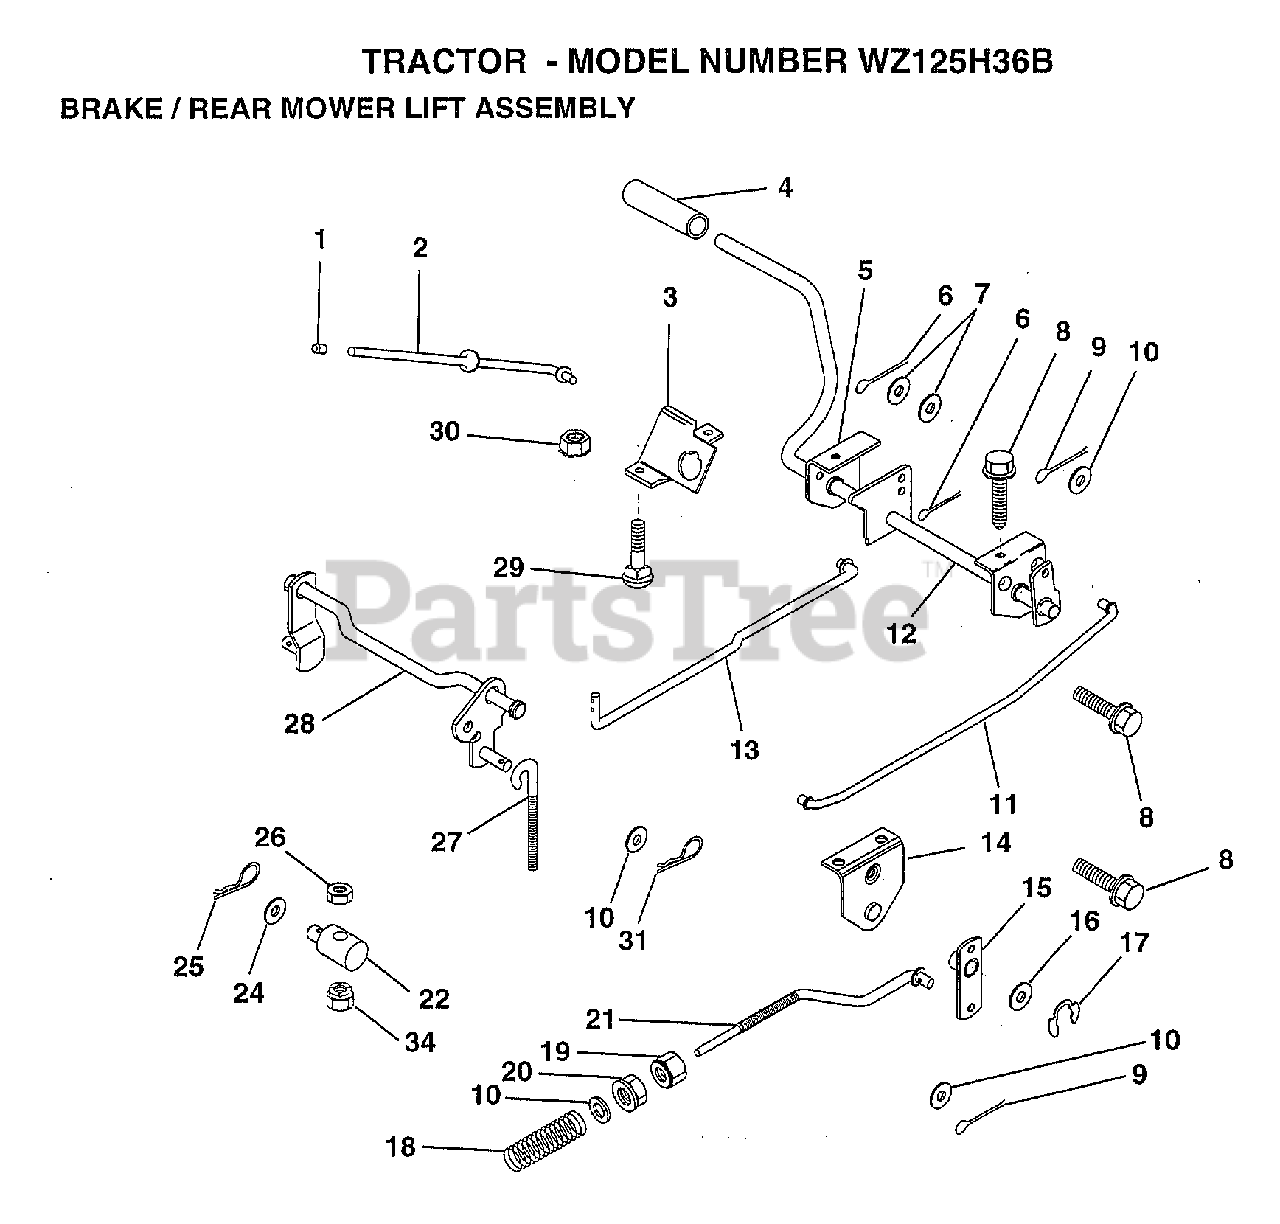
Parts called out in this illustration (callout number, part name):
1	PLUNGER CAP T
2	"ROD,PARK BRAKE"
3	"BRKT,PARK BRAKE"
4	FOOT PEDAL COVER
5	"BRKT,CLU PEDAL LH"
7	WASHER
8	SCREW LT
9	COTTER PIN
10	WASHER
11	"ROD,FRT BRAKE"
12	PEDAL ASM CL/BK36
13	"ROD,CLUTCH"
14	"BRKT,LIFT SHAFT"
15	PVT BRAKE ARM ASM
16	WASHER T
17	KLIP RING
18	SPRING ROD BRAKE
19	NUT
20	NUT
21	ROD.BRAKE.HYDRO
22	TRUNNION.LIFT.
24	WASHER
25	SPRING.RETAINER
26	LOCKNUT
27	LINK, THREADED
28	LIFT ASM MOW REAR
31	RETAINER.SPRING
